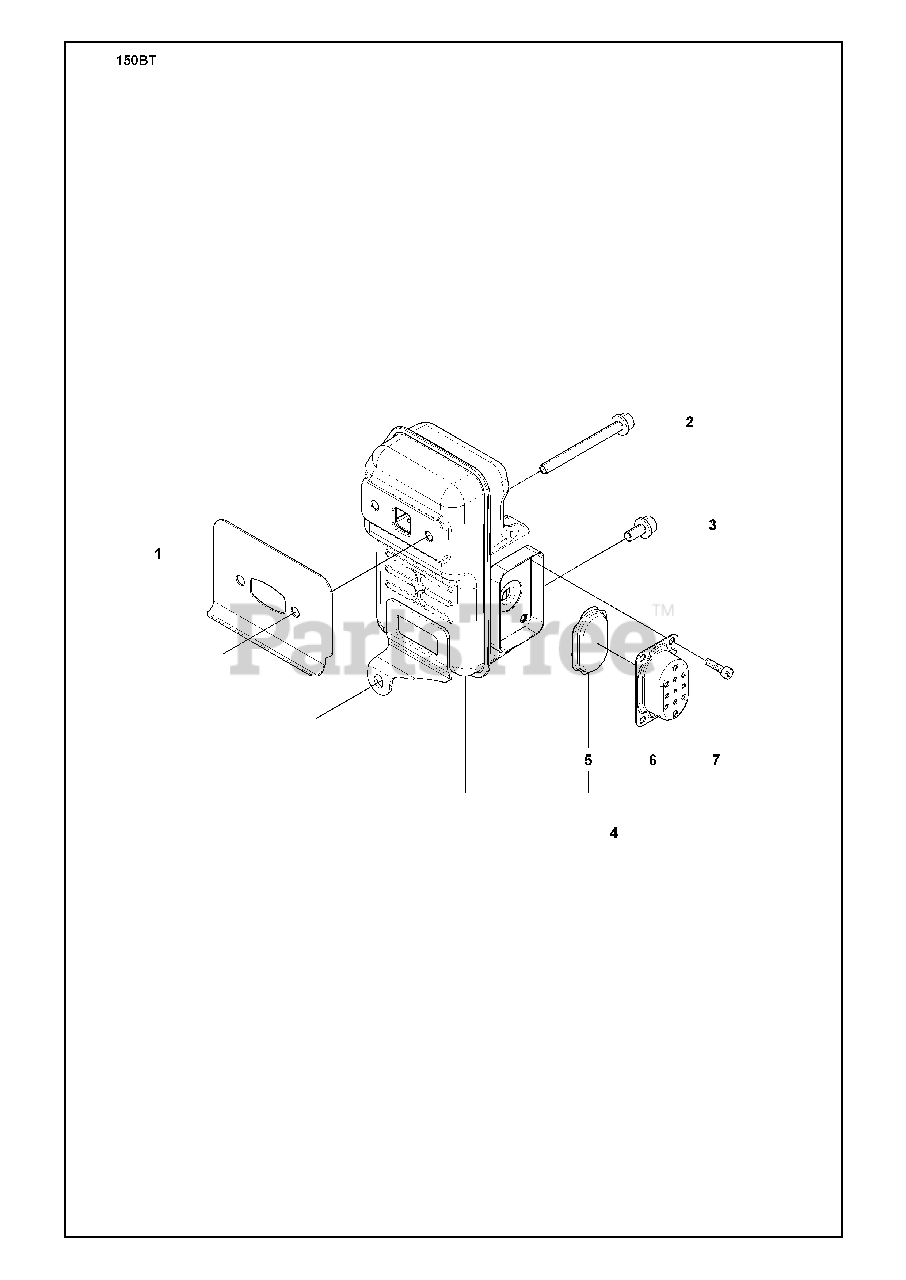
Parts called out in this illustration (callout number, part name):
1	GASKET
3	RP_BOLT
4	MUFFLER ASSY
5	SPARK ARRESTOR SCREEN
6	EXHAUST DUCT
